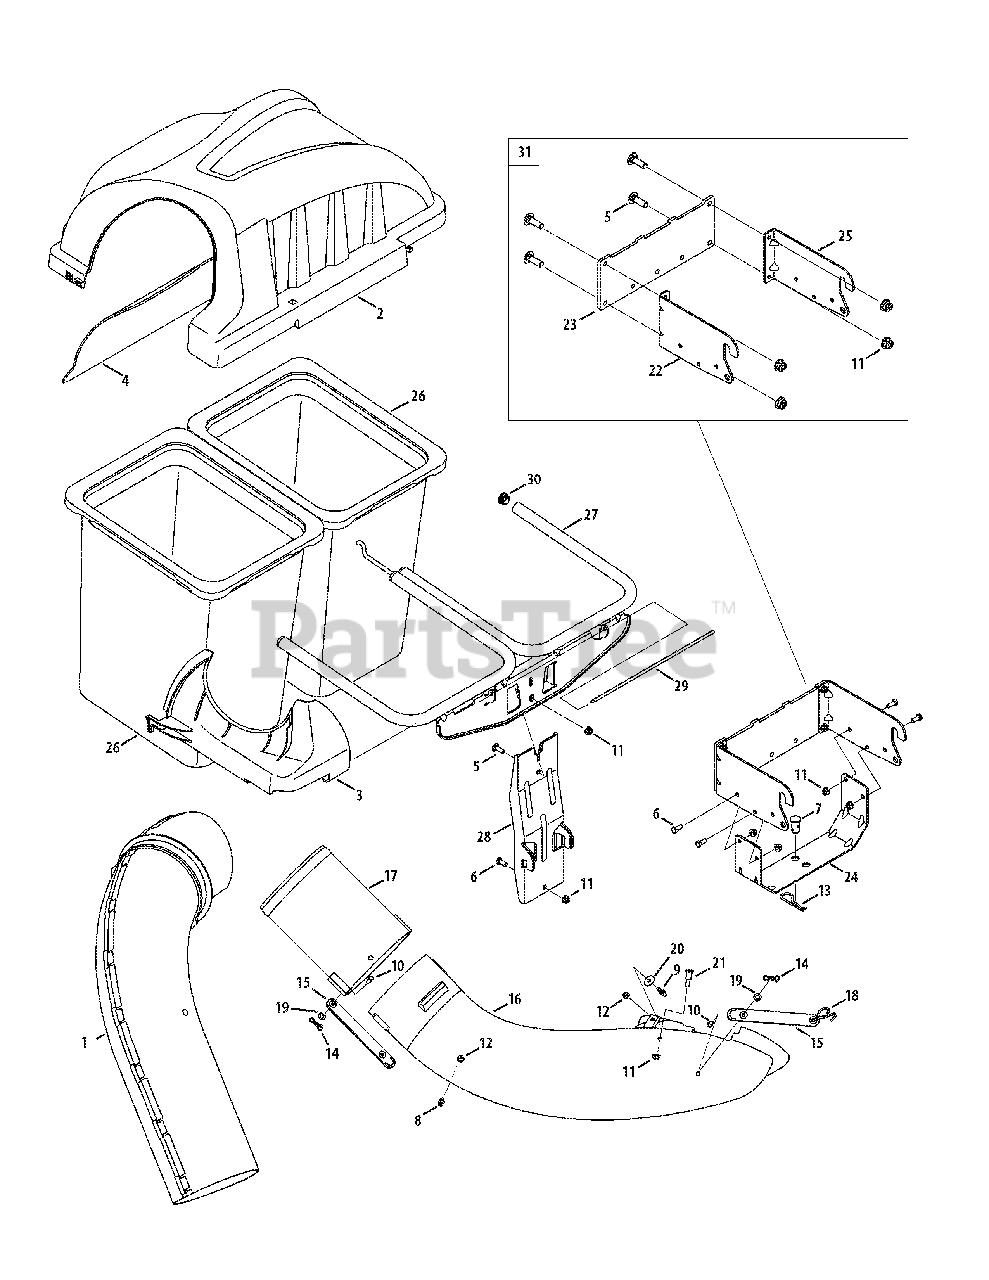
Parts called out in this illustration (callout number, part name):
1	Upper Chute Assembly
2	Double Bagger Cover Assembly
3	Upper Chute Support
4	Bagger Cover Screen
5	Carriage Screw, 5/16-18 x 1.00"
6	Hex Head Screw, 5/16-18 x .75"
7	Clevis Pin, .62" Dia.
8	Grass-catcher Pin, 1/4-20
9	Attachment Pin, 1/4 x 0.66 Lg.
10	Clevis Pin, 5/16 x .75 Lg.
11	Flange Lock Nut, 5/16-18
12	Flange Lock Nut, 1/4-20
13	Internal Cotter Pin, .148 x 3.00
14	Bow-Tie Cotter Pin, 72
15	Chute Strap, 6.00 Lg.
16	Bagger Discharge Chute, Elbow
17	Bagger Chute Adapter, 7 In.
18	Torsion Spring Hook
19	Flat Washer, .344 x .62 x .033
20	Flat Washer, .265 x .938 x .120
21	Shoulder Screw, .437 x .54
22	Mounting Bracket, RH
23	Universal Mounting Bracket
24	Universal Bracket Support
25	Mounting Bracket, LH
26	Grass-bag Assembly
27	Double Bag Support Assembly
28	Vertical Support Bracket
29	Cover Hinge Pin
31	Mounting Bracket Kit (Incl. ref. 22, 23, 25)
